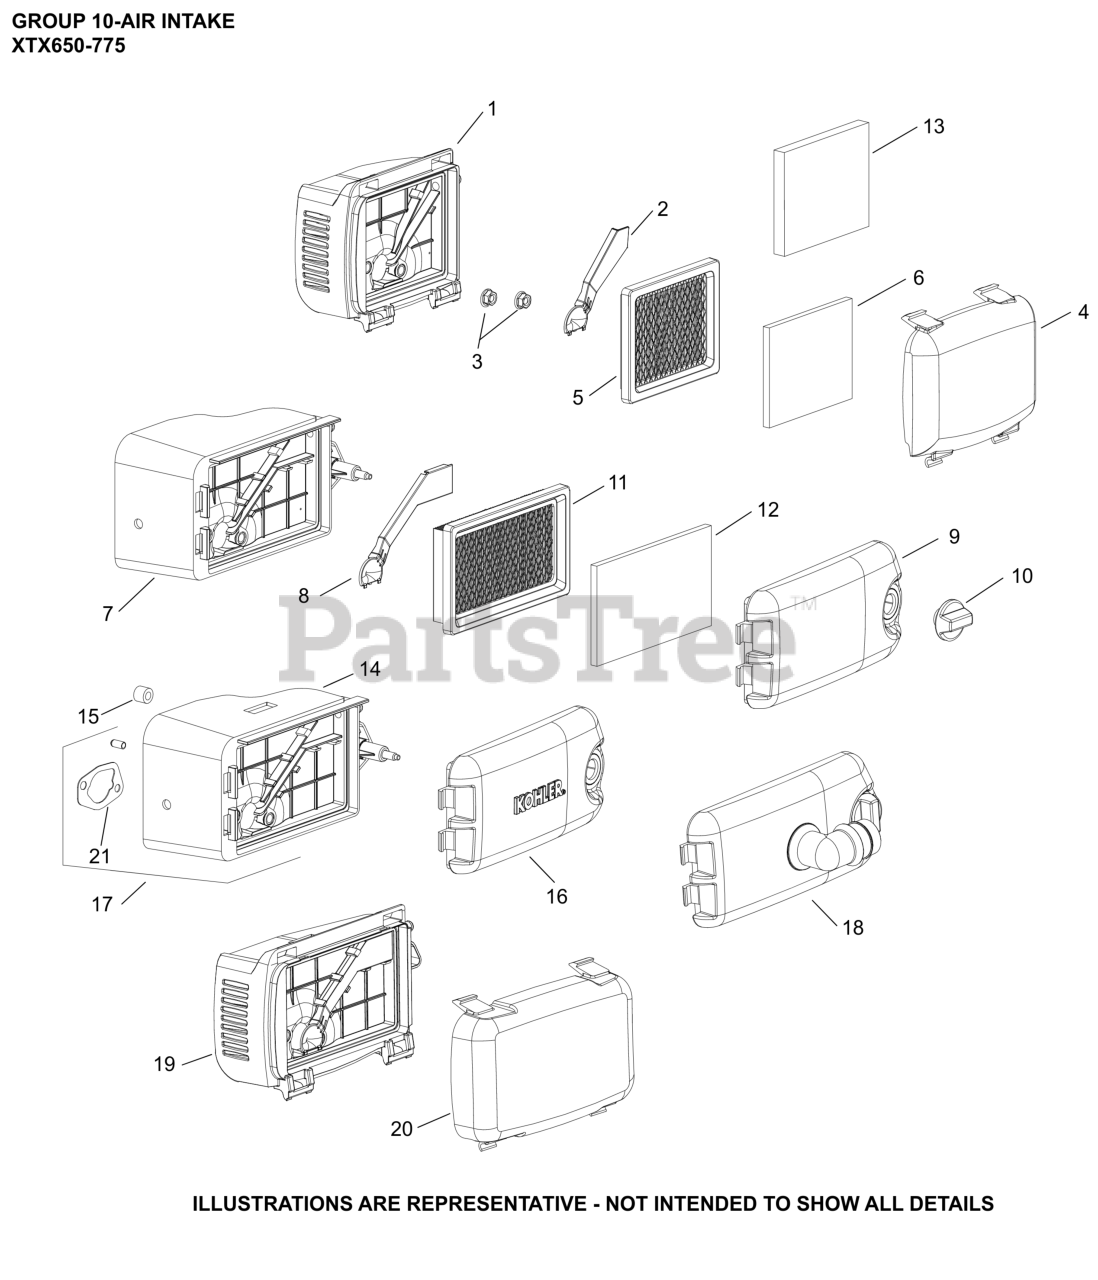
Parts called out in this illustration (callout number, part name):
7	KIT, AIR CLEANER BASE
8	COVER, A/C BASE (BREATHER GAS)
9	COVER, AIR CLEANER
10	KNOB-USE 14 341 07-S
11	ELEMENT, AIR FILTER
12	ELEMENT, PRE-CLEANER
21	GASKET, AIR CLEANER BASE
